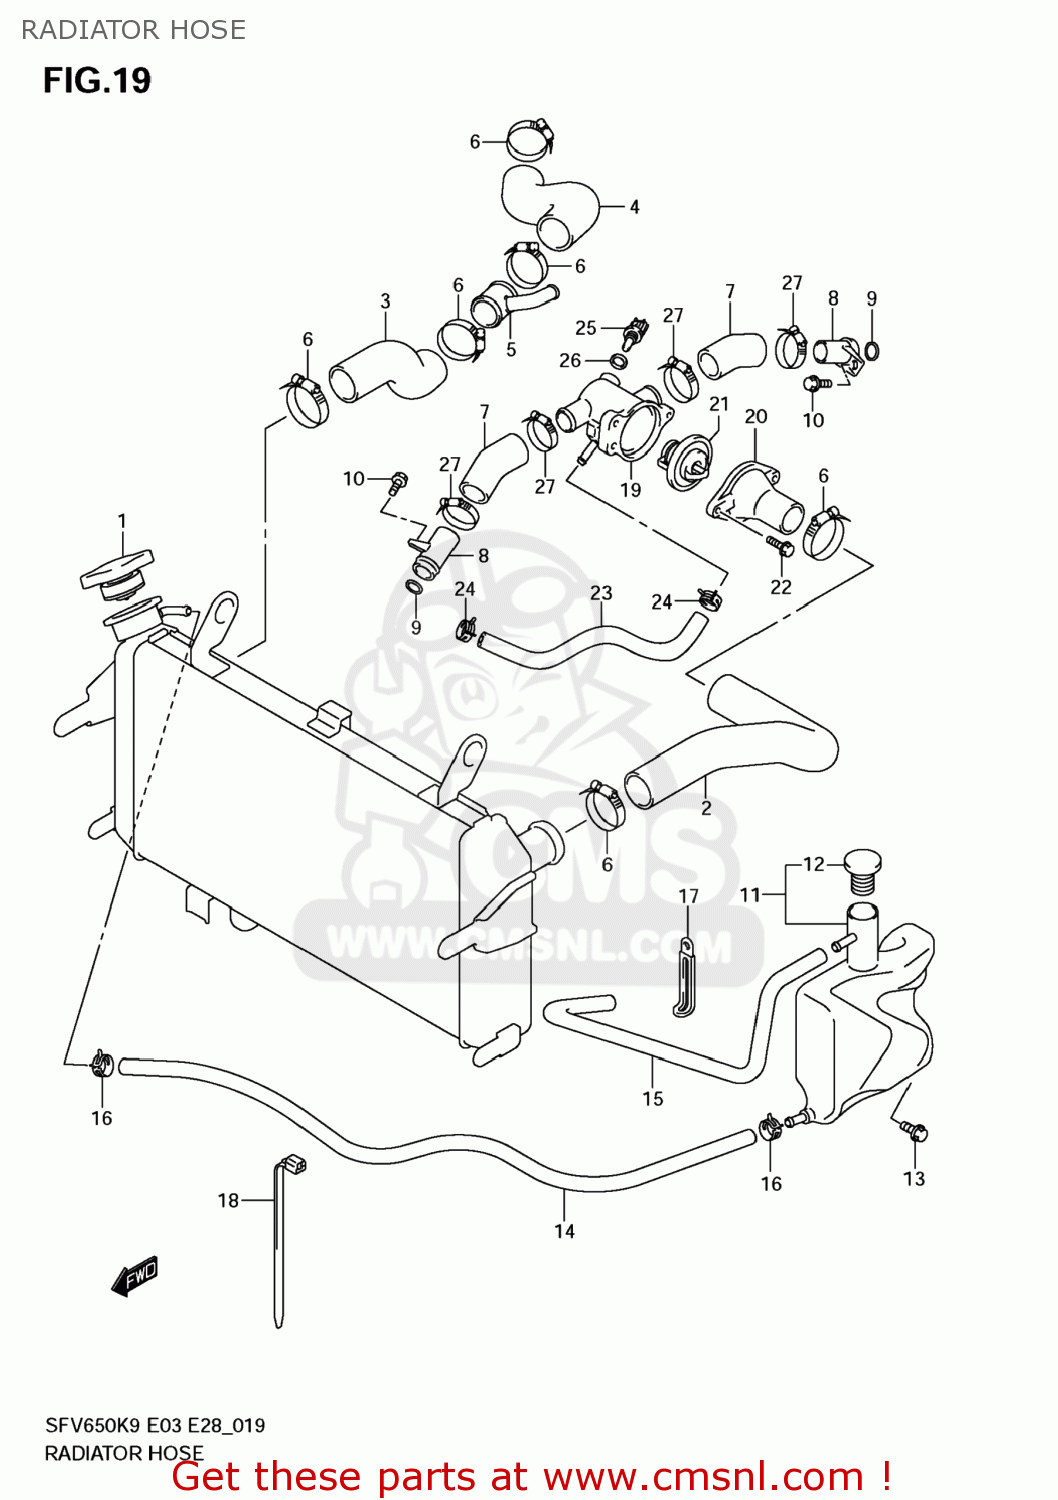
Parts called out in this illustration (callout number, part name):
1	CAP,RADIATOR
2	HOSE,RADIATOR INLET
3	HOSE,RADIATOR OUTLET NO.1
4	HOSE,RADIATOR OUTLET NO.2
5	UNION,WATER HOSE THREE WAY
6	CLAMP
7	HOSE,CONNECTOR INLET
8	UNION,CONNECTOR HOSE
9	O RING(D:3.2,ID:17.8)
10	BOLT
11	TANK ASSY,RESERVOIR
12	CAP,RESERVOIR TANK
13	BOLT(6X12)
14	HOSE,RESERVOIR TANK INLET
15	HOSE(5X9X600)
16	CLIP
17	CLAMP(L:45)
18	CLAMP(L:190)
19	CONNECTOR,THERMOSTAT INLET
20	CAP,THERMOSTAT CONNECTOR
21	THERMOSTAT,WATER
22	BOLT
23	HOSE,CONNECTOR TO WATER PUMP
24	CLAMP
25	SENSOR,TEMP
26	GASKET(12X17X1) (NAS)
27	CLAMP
